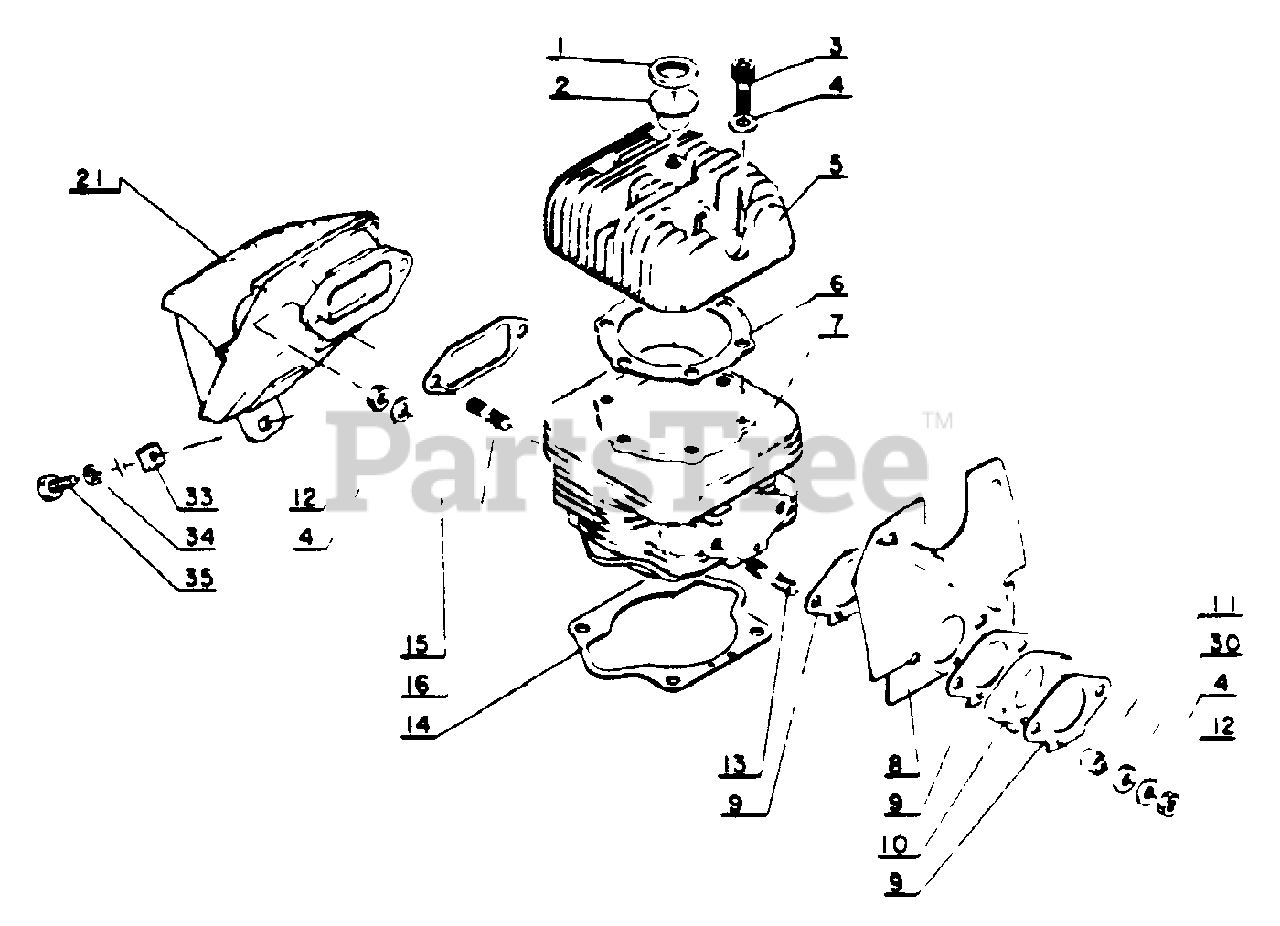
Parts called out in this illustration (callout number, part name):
1	INSULATOR
2	INSULATOR
3	BOLT - 6×22
4	WASHER 6.5×11.5×0.8
5	HEAD, CYLINDER
6	GASKET, CYLINDER
7	CYLINDER
8	PLATE, WIND PROOF
9	GASKET, INTAKE
10	INSULATOR, INTAKE
11	SPACER
12	LOCKNUT - 6
13	STUD
14	GASKET, CYLINDER
15	GASKET, EXHAUST
16	STUD
21	MUFFLER
30	INSULATOR
33	NUT
34	WASHER, SPRING 5
35	BOLT
35	BOLT 5×12
